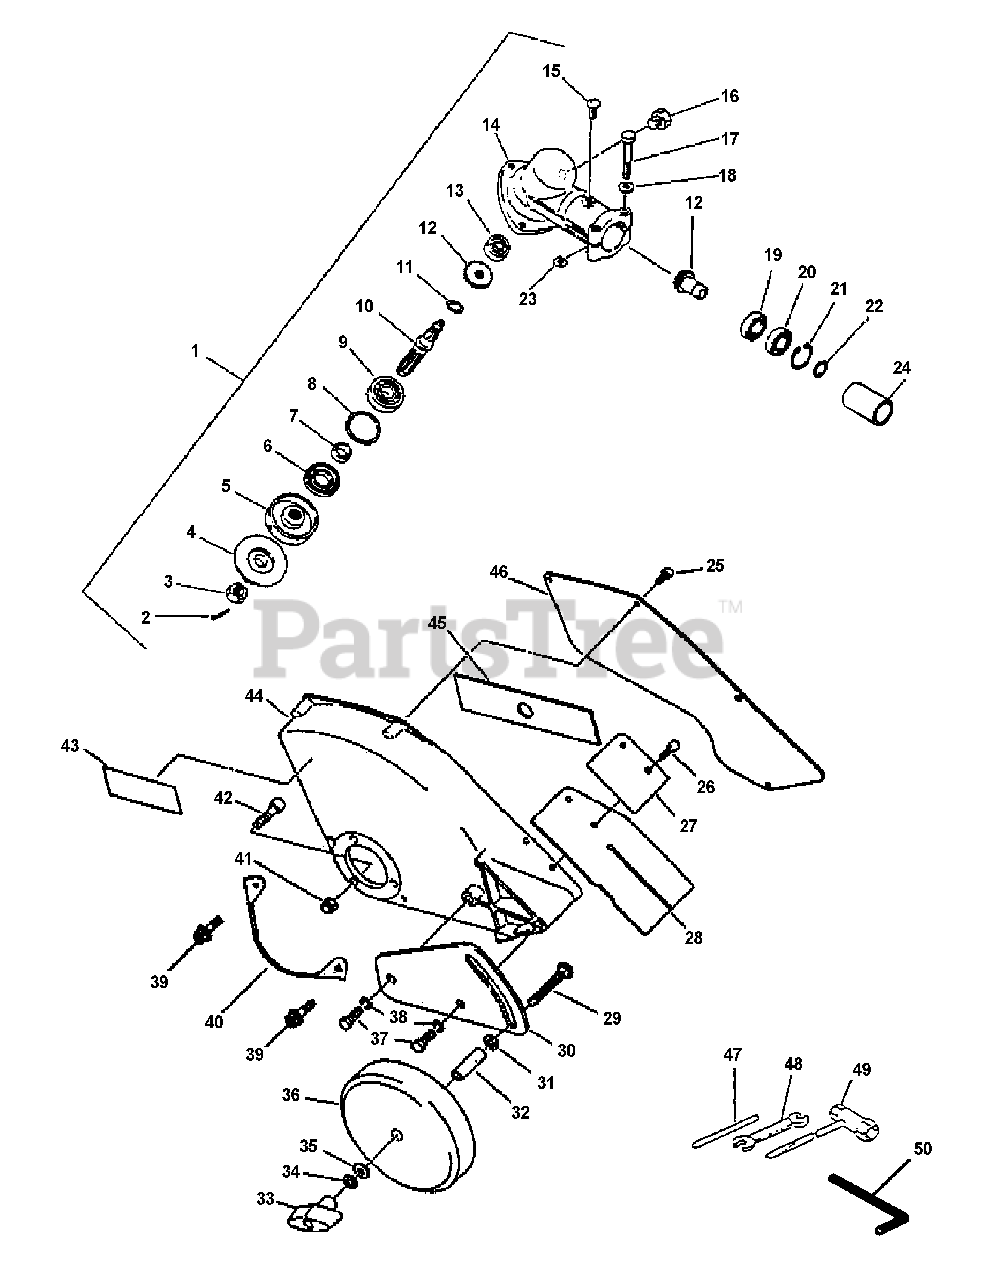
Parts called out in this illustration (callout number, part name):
1	GEAR CASE ASSY
2	PIN, SPLIT - 2X22
3	LOCKNUT - LEFT HAND
4	ADAPTOR, BLADE - LOWER
5	ADAPTOR, BLADE - UPPER
6	SEAL, OIL
8	RING, RETAINING - 32
9	BEARING, BALL - 6201
10	GEAR - SHAFT
11	RING, RETAINING - 12
12	GEAR SET
13	BEARING, BALL - 6000
14	CASE, GEAR
15	SCREW - 5X10
16	BOLT - 8X8
17	BOLT - 5X40
18	WASHER - 5
19	BEARING, BALL - 6001C3
20	BEARING, BALL - 6001
21	RING, RETAINING - 28
22	RING, RETAINING - 12
25	SCREW - 4X12
26	SCREW - 4X14
27	FLAP, DEBRIS
28	FLAP, DEBRIS
29	BOLT - CARRIAGE
30	BRACKET, WHEEL
31	WASHER - 10
32	COLLAR - 12
33	WINGNUT - 5/16-18
34	LOCKWASHER - 8
35	WASHER - 8
36	WHEEL - 6X1.5
37	BOLT - 8X14
38	LOCKWASHER - 8
39	SCREW - 4X12
41	LOCKNUT - 5
42	SCREW - 5X22
43	LABEL - CAUTION
44	NEW BLADE SHIELD
45	BLADE, EDGER
46	COVER, SHIELD
47	LOCKING TOOL
48	SPANNER - 8X10mm
49	T-WRENCH - 17X19mm
50	HEX KEY - 3mm
